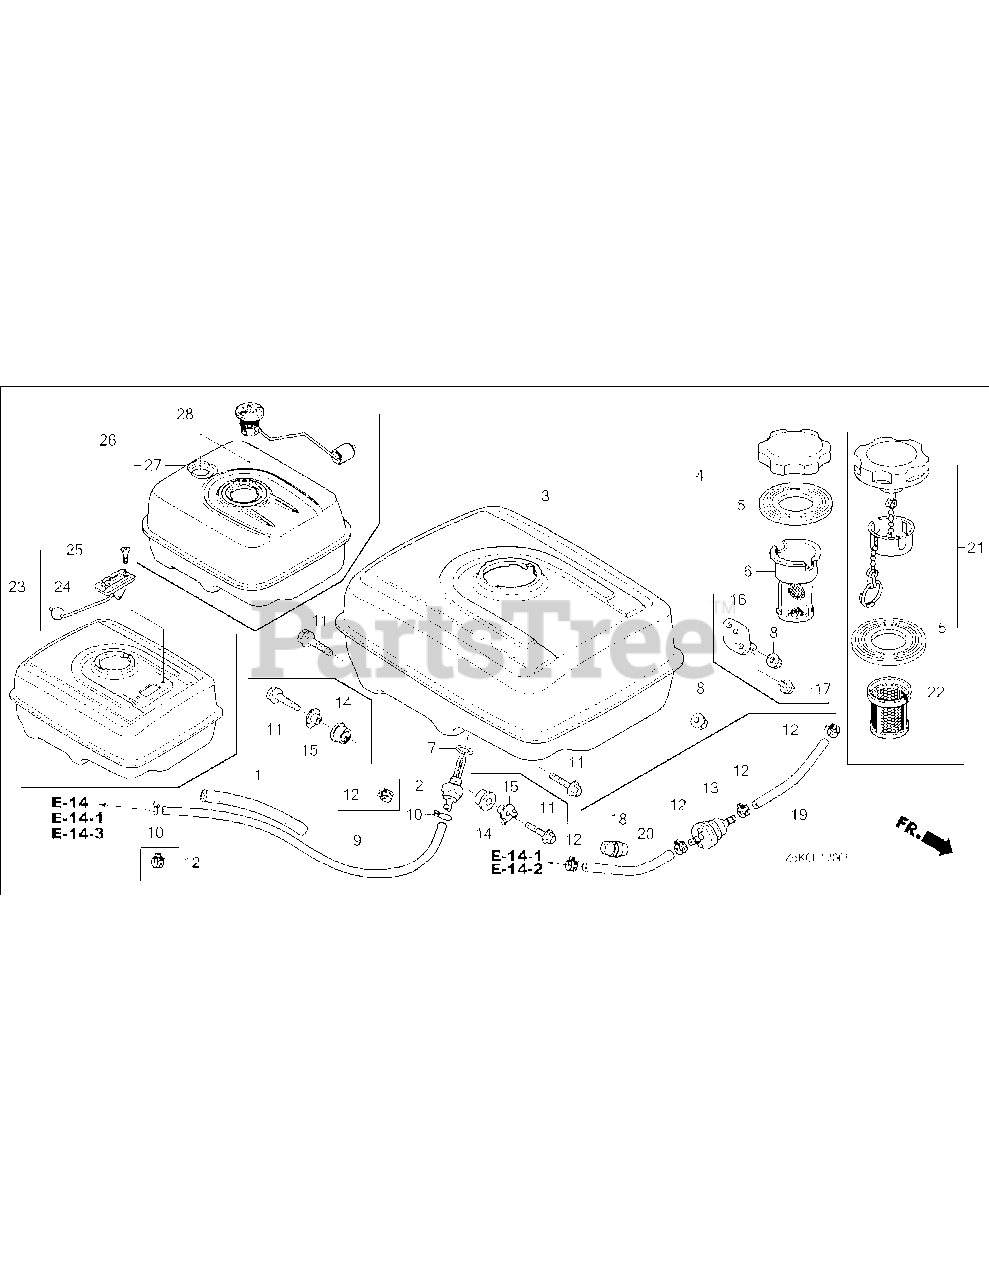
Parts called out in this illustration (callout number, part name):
1	Rubber, Supporter(107Mm)
2	Joint, Fuel Tank
3	Tank Comp., Fuel
4	Cap Comp., Fuel Filler(Chrome Plated)(Radicon)
5	Packing, Fuel Filler Cap(39X62X3)
6	Filter, Fuel
7	O-Ring, 14Mm(Nok)
8	Nut, Flange, 8Mm
9	Tube, Fuel, 4.5X210(Fkm)
10	Clip, Tube(B8)
11	Bolt, Flange, 8X25
12	Clamp, Tube(D8)
13	Strainer Comp., Fuel
14	Rubber A, Tank Mounting
15	Nut, Tank Mounting
16	Rubber Comp., Tank Mounting
17	Bolt, Flange, 6X10
18	Rubber, Fuel(9X15X20)
19	Tube, Fuel, 4.5X150(Fkm)
20	Tube, Fuel, 4.5X120(Fkm)
21	Cap Comp., Fuel Filler
22	Filter, Fuel
23	Tank Assy., Fuel(Gauge)
24	Gauge Assy., Fuel
25	Screw, Flat, 5X10
26	Tank Assy., Fuel(Gauge)
27	Tank Comp., Fuel
28	Gauge Assy., Fuel
